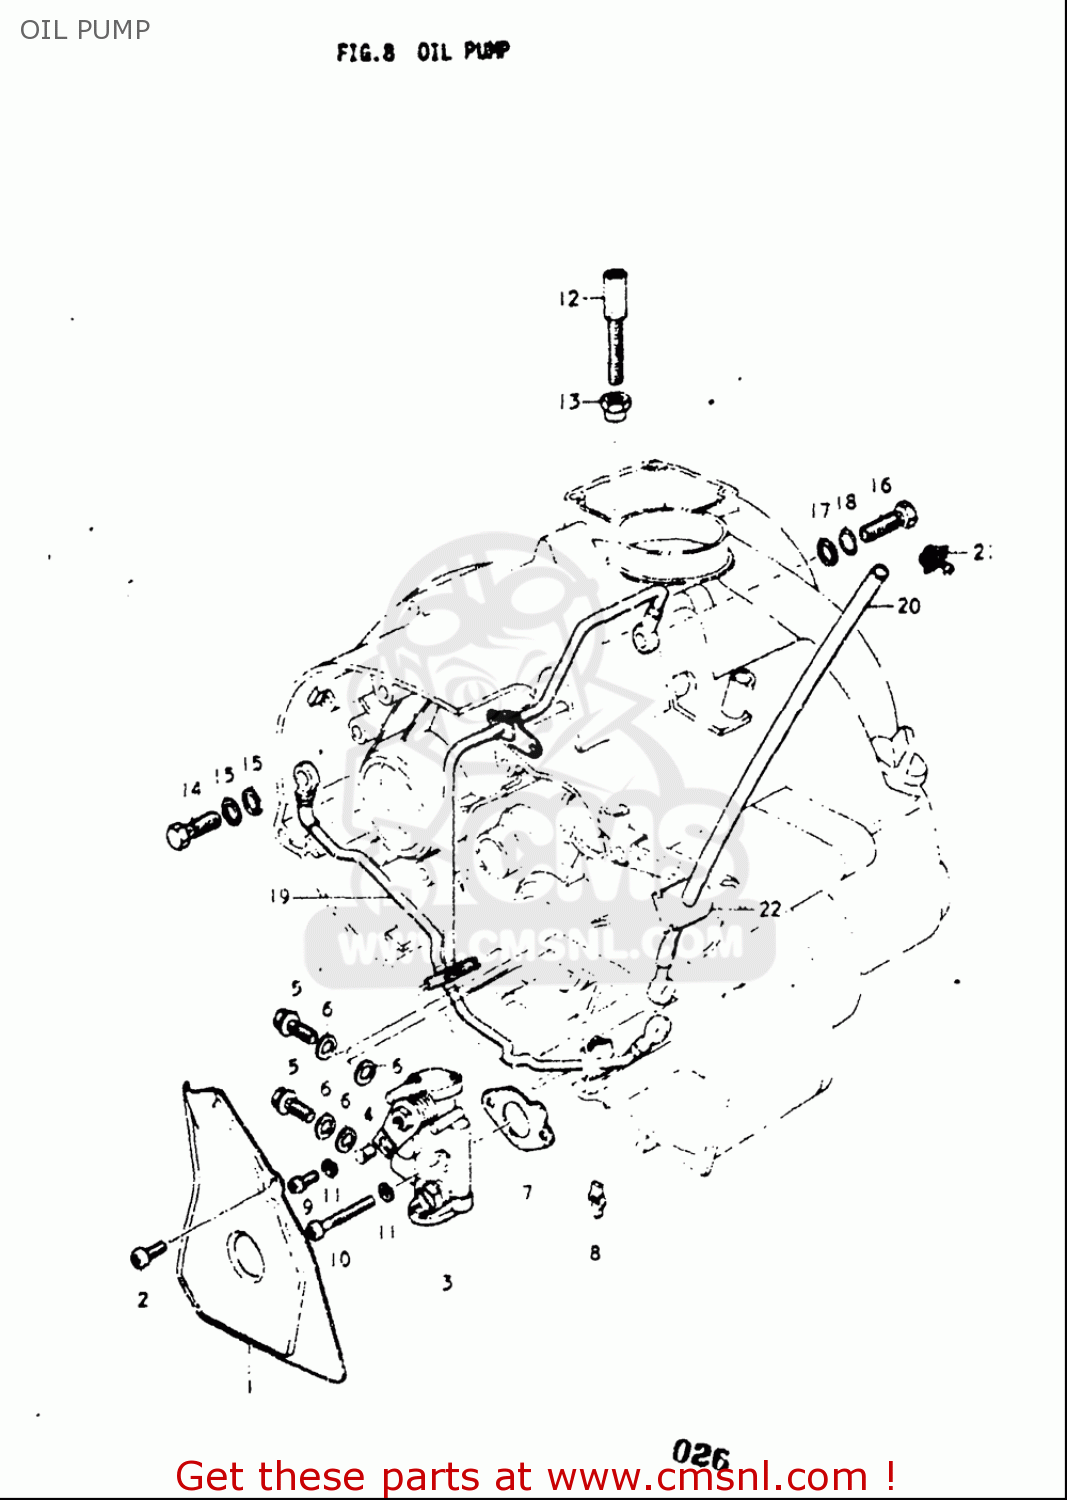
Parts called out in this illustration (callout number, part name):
2	SCREW
4	TERMINAL,CABLE
5	UNION
6	GASKET(6.2X11X1).2 (NAS)
7	GASKET,OIL PUMP (NAS)
8	PIECE,OIL PUMP DRIVE
9	SCREW
10	SCREW
11	WASHER,LOCK
12	BOLT
13	NUT
14	UNION BOLT
15	GASKET(6.2X11X1).2 (NAS)
16	CHECK VALVE,INLET
17	GASKET(10X16X3) (NAS)
18	O RING(D:1.3,ID:7.6)
20	HOSE,INLET
21	CLAMP
22	GROMMET
